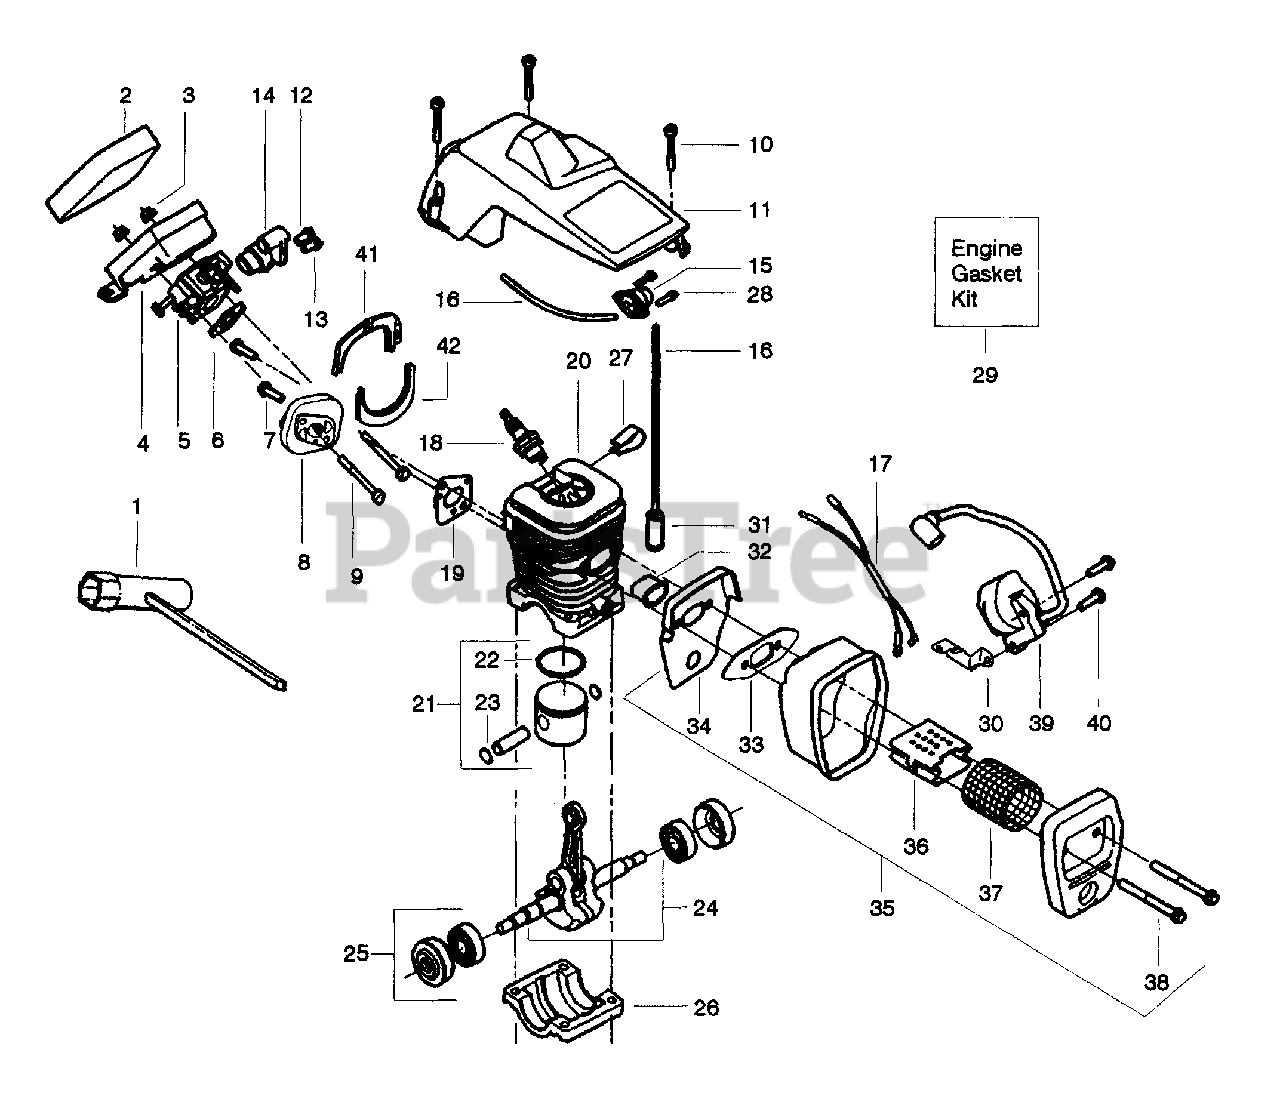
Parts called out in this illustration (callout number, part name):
1	Bar Wrench
2	Foam-Air Filter
4	Air Filter Housing
5	Carburetor Kit
6	Carb. Gasket
7	Screw
8	Carb. Adapter
11	Cylinder Shield
12	Limiter Cap-High
13	Limiter Cap-Low
14	Grommet-Carb Adjust
15	Air Purge Ass'y.
16	Fuel Line Kit (Small)
17	Wire Harness Ass'y.
18	Spark Plug (CJ-7Y)
19	Gasket-Carb Adaptor
20	Cylinder Kit
21	Piston Kit
22	Piston Ring
23	Retainer-Piston Pin
24	Crankshaft Ass'y.
25	Seal & Bearing Ass'y.
26	Cap-Crankcase
27	Clip-High Tension Lead
29	Engine Gasket Kit
30	Ground Strap
31	Fuel Pick-up Ass'y.
32	Heat Insulator
33	Muffler Gasket
34	Muffler Backplate
35	Muffler Ass'y.
36	Muffler Diffuser
37	Spark Screen
39	Ignition Module
41	Seal-Carb Adapter-(Upper)
42	Seal-Carb Adapter-(Lower)
